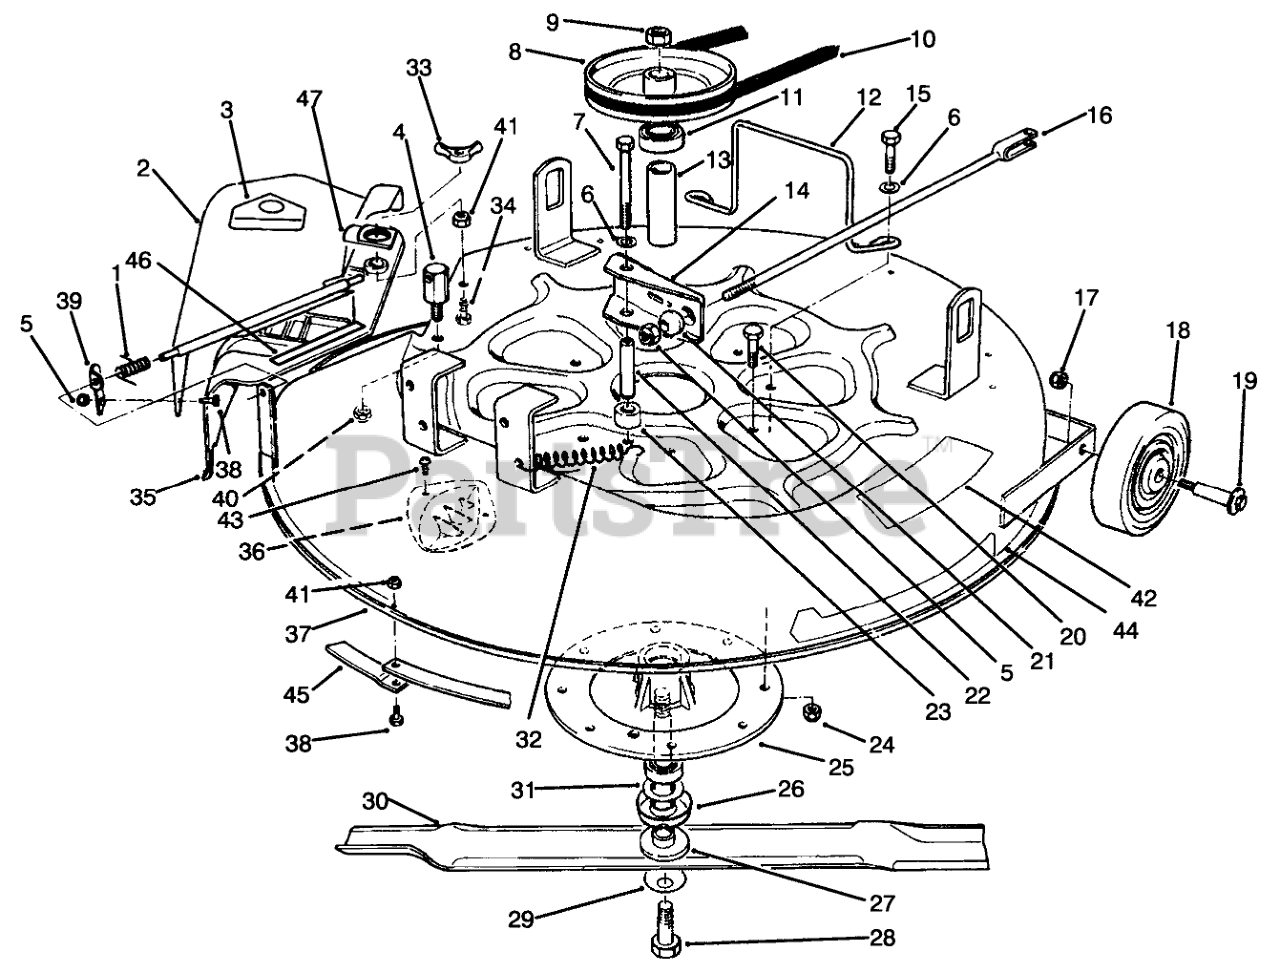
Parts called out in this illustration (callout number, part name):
1	SPRING
2	Deflector (Incl. Ref. #3)
3	DECAL-DANGER
4	POST-PIVOT
5	NUT-HEX
6	WASHER-PLAIN
7	SCREW-HH
8	PULLEY-DECK
9	NUT-HEX
10	V-Belt
11	BEARING-BALL
12	GUIDE-DECK BELT
13	SPACER-BEARING
14	DECK BRAKE ASSEMBLY
15	SCREW-HH
16	DECK BRAKE ROD WA
17	NUT-LOCK, NI
18	WHEEL-DECK
19	BOLT-WHEEL
20	SCREW-HH
21	BALL-SWIVEL, STOP
22	POST-BRAKE MTG
23	SPACER-DECK BRAKE
24	NUT-LOCK, NI
25	CASTING-SPINDLE
26	SHIELD-BEARING
27	SHAFT-SPINDLE
28	SCREW-HH
29	WASHER-BELLEVILLE
30	Blade
31	SPACER
32	SPRING-EXTENSION
33	Nut-Wing
34	SCREW-HHF
35	COVER- 25" (W/KICKER)
36	KICKER
37	Deck (Incl. Ref. #42)
38	SCREW-HH
39	BRACKET-DEFLECTOR
40	NUT-LOCK, NI
41	NUT-LOCK, NI
42	DECAL - DANGER
43	SCREW-PPH
44	DECAL - RECYCLER 25"
45	25" RECYCLER RING (BLACK)
46	DECAL-DANGER, DEFLECTOR
